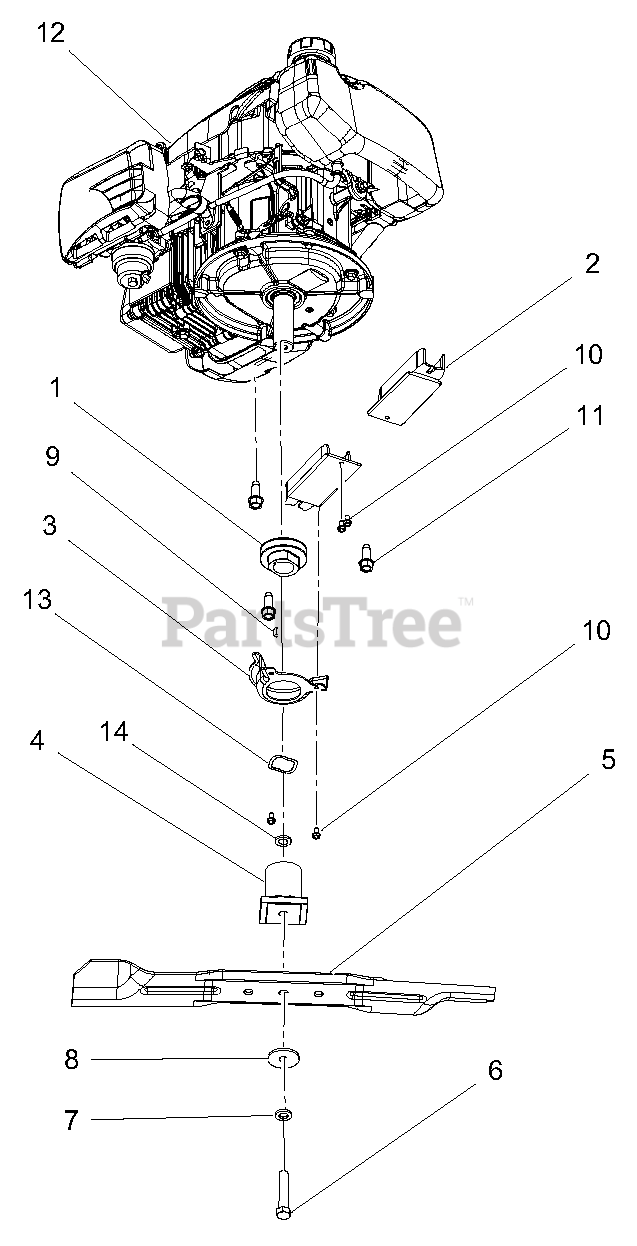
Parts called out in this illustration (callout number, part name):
1	PULLEY, GROUND DRIVE, LM (911174, 178)
2	GUIDE, BELT - INNER
3	GUIDE, BELT CRANKSHAFT (911174, 178)
4	ADAPTOR, BLADE
5	BLADE, MOWER 21" HIGH-LIFT
6	@BLT-HEX .44-20X2.25 GR8 YWZC
7	@WSHR-LK .44X.109 REG YWZC
8	WSHR-FL-STL .4375X1.50X.125 YWZC
9	KEY-SQ .188X.188X.625 (911174, 178)
10	SCR, TAP 10-24X.375 PRE-COAT 80 (911174, 178)
10	SCR, TAP 10-24X.375 PRE-COAT 80 (911172)
11	SCR-TAP .38-16X1.00 HWH TR YZ
12	ENGINE, SUBARU (911174)
12	ENGINE, SUBARU, ELECTRIC (911178) N/S
12	ENGINE, SERVICE, AC SERIES (911172) N/S
13	WASHER, WAVE (911174, 178)
14	WSHR-FL-STL .459X.750X.105 YWZC, 911174 (ENGINE S/N 0-1014400), 911178 (ENGINE S/N 0-1014670)
